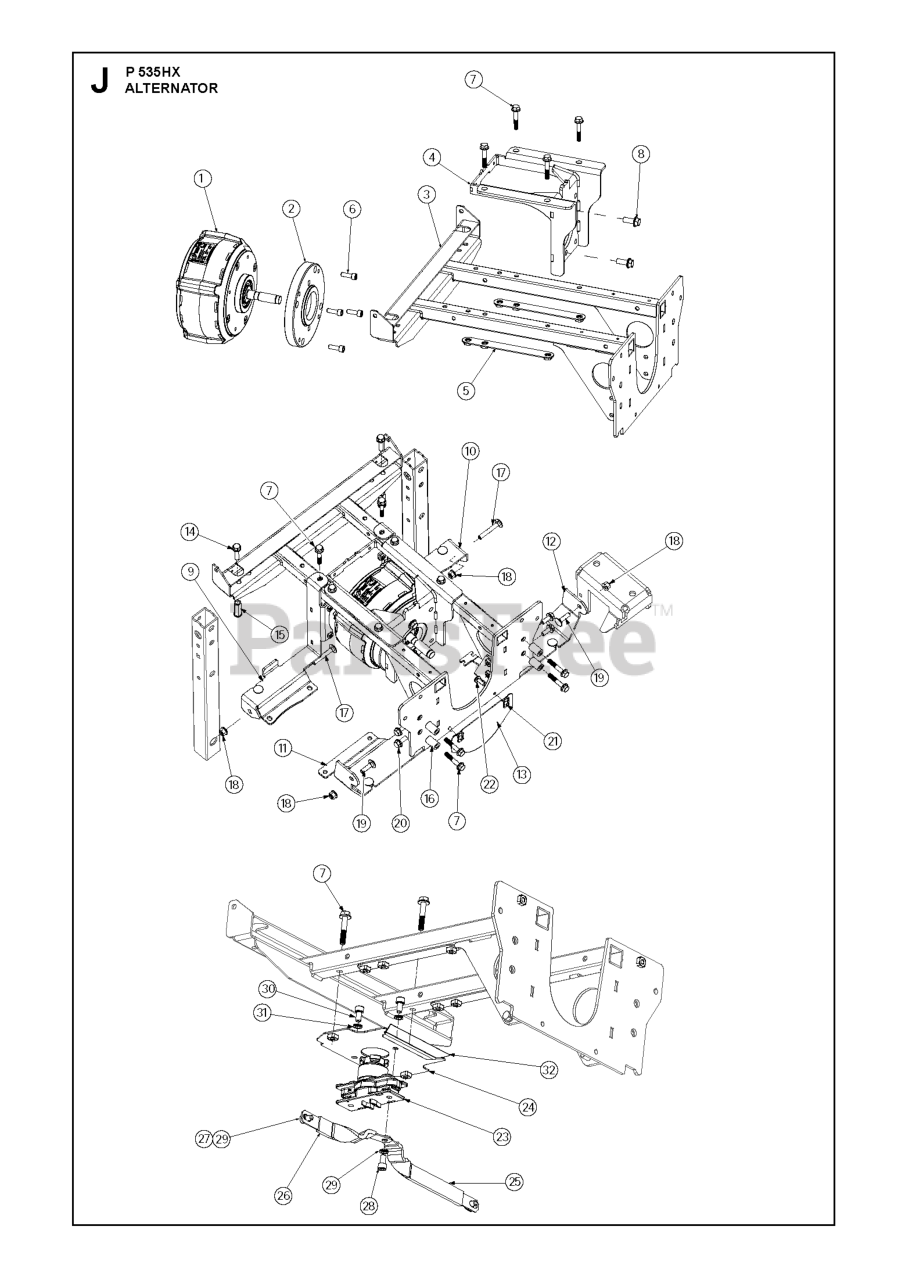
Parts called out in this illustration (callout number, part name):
14	SCREW EHHFM
18	NUT FLANGE
31	WASHER LOCK 8.7X13.5X2.5 ZN FL
